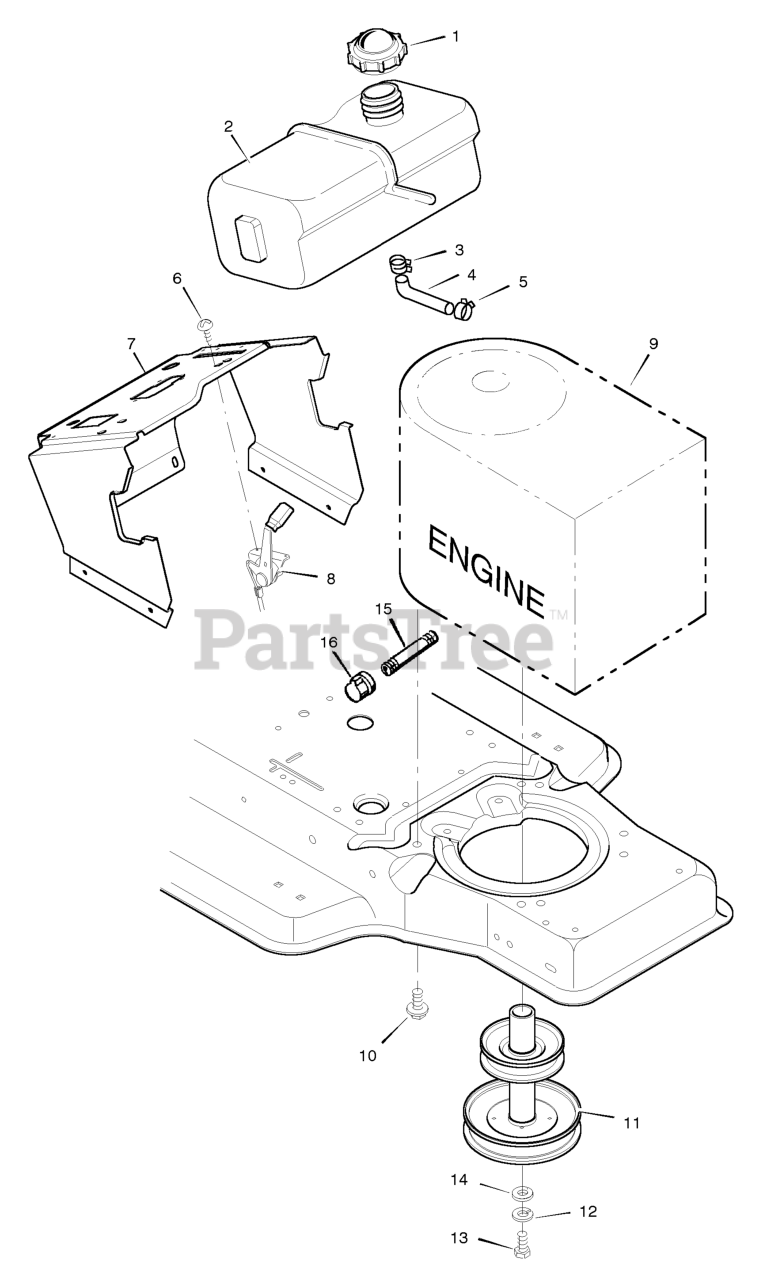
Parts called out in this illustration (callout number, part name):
1	Fuel Cap
2	Fuel Tank
3	Hose Clamp
4	Fuel Line
5	Hose Clamp
7	Support, Dash
8	Throttle Control
9	Engine *
10	Bolt, Engine Mount
11	Stack Pulley Assembly
12	Lockwasher
13	Bolt, Hex
15	Pipe, Oil Drain
16	Cap, Oil Drain
